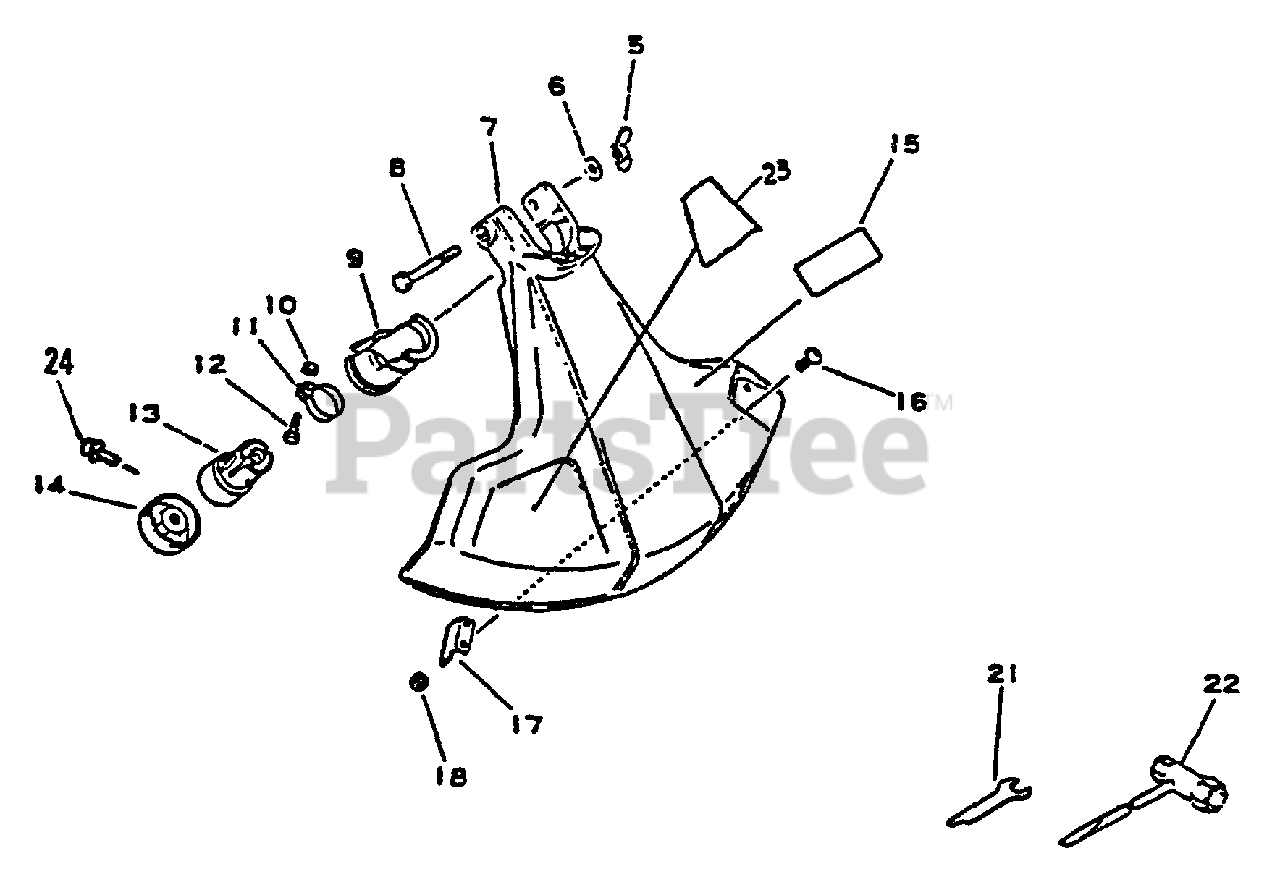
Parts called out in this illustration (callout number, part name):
5	NUT, WING 6
6	WASHER 6.5×11.5×0.8
7	SHIELD
8	BOLT - 6×50
9	BRACKET, BEARING CASE
10	NUT M5
13	GEAR CASE ASSY
14	PLATE, ADAPTER - UPPER
15	LABEL - ECHO
16	SCREW 5×16
17	CUTTER, LINE
18	NUT M5
22	WRENCH
23	LABEL, CAUTION
24	SCREW 4×10
